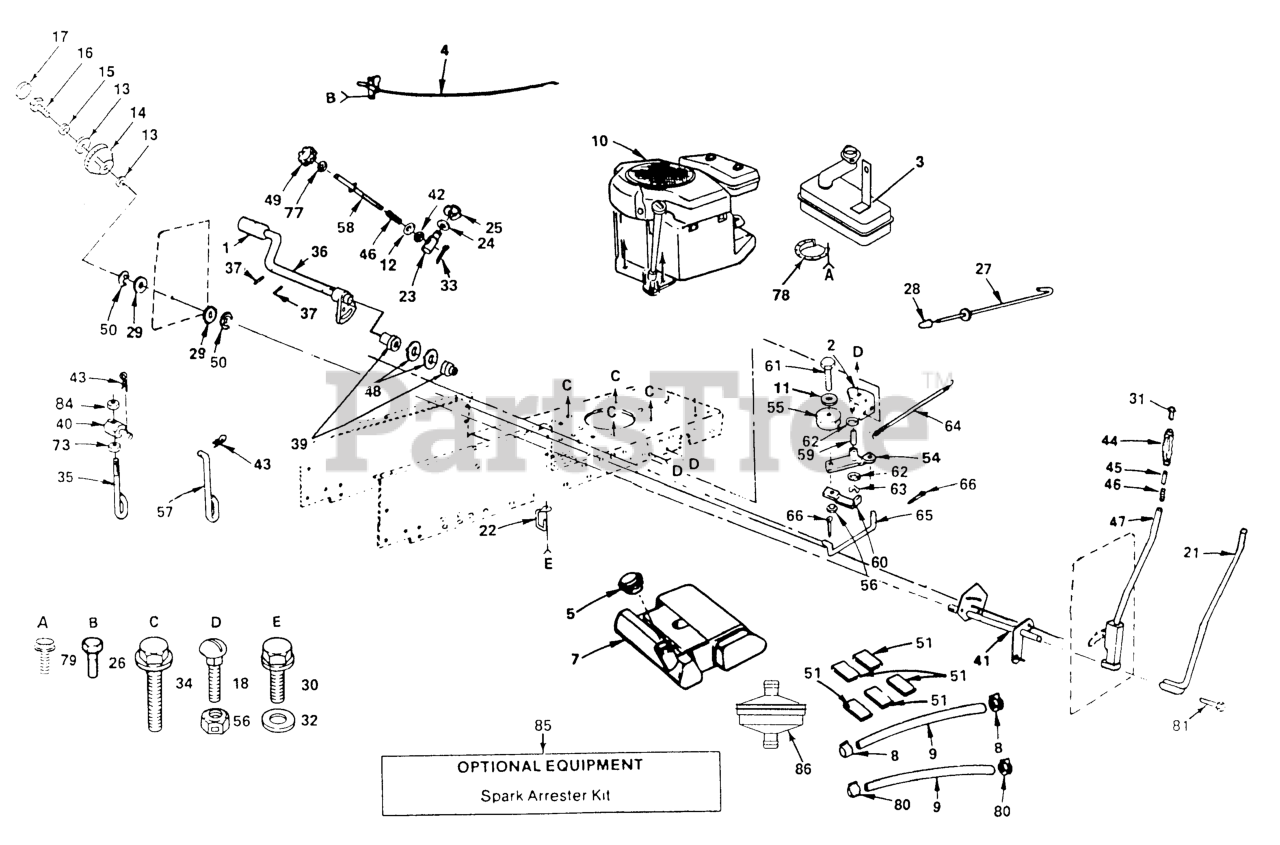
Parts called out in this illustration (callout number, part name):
1	PEDAL COVER T
3	MUFFLER
4	CONTROL
5	FUEL CAP ASS'Y
7	FUEL TANK LT
8	HOSE CLAMP
9	FUEL LINE T
10	Engine 12.5 HP
11	WASHER
14	HEIGHT INDICATOR
15	WASHER.LOCK.HVY.HLCL.SPR.5/16
16	BOLT.FIN.HEX.5/16-18UNC X 1.00
18	Bolt, Carriage, 3/8-16 x 3/4
21	LEVER ROD LT
22	RETAINER-BELT LT
23	TRUNION LT
24	Washer, 15/32 x 3/4 x 16 Ga.
26	SCREW LT
27	ROD BRAKE PARK
28	PLUNGER CAP
29	Washer, 29/32 x 1 - 1/4 x 16 Ga
30	SCREW
31	PLUNGER BUT KIT
32	WASHER
33	COTTER PIN
35	LINK ADJ T
36	SHAFT FOOT PEDAL
37	PIN.ROLL.3/16 X 1"
39	BEARING.NYLON
40	TRUNNION T
41	SHAFT LIFT
43	RETAINER-SPRNG RB
45	PLUNGER BUT KIT
46	SPRING**
47	LIFT LEVER KIT
48	WASHER LT
49	HDLE ADJ LIFT
51	PAD-SPACER T
55	IDLER PULLEY
56	LOCKNUT
57	LIFT LINK LT
58	ROD LIFT LT
59	BEARING LT (2 2)
60	RETAIN BELT
61	BOLT
64	SPRING, RETURN LT
65	LINK, CLUTCH LT
66	COTTER PIN
73	NUT **
77	NUT
78	DEFL MUFFLER LTV
79	NUT.CROWNLOCK.1/4
80	REPL BY 532 12 34-87
81	BOLT
84	NUT LOCK YTH
85	SPARK ARREST KIT
86	FILTER,FUEL
